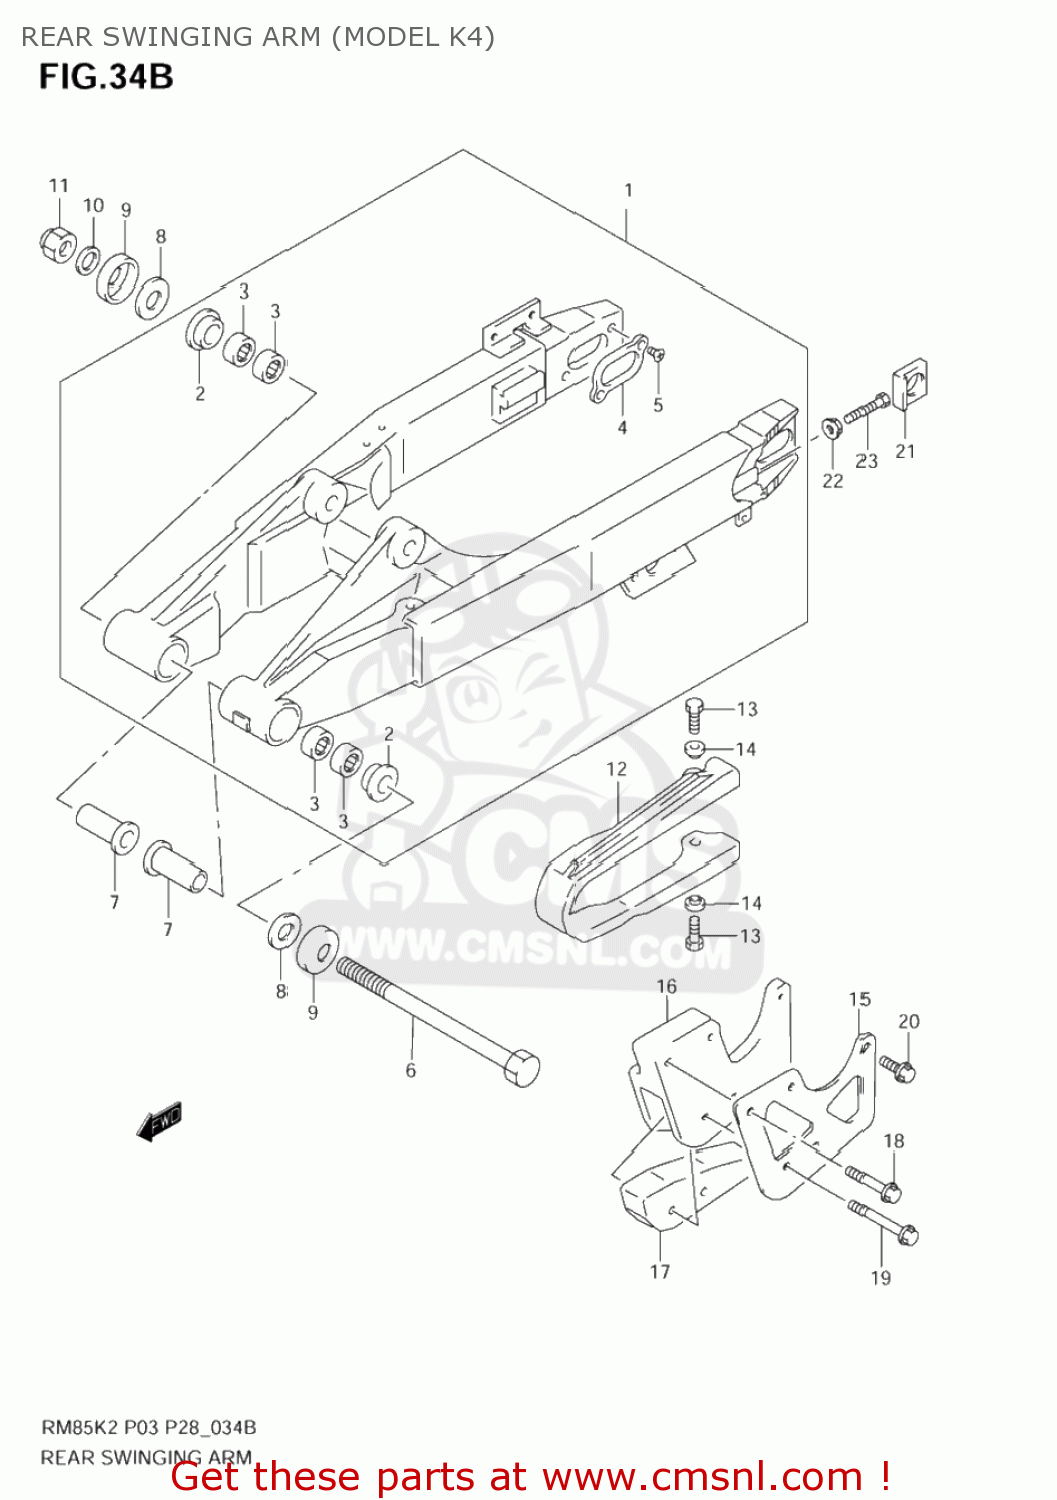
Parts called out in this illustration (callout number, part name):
1	SWINGINGARM AS
2	BUSHING,SWGARM PIVOT
3	BEARING(17X24X20)
4	PLATE,SWGARM RR
5	SCREW,UPPER
6	SHAFT,RR SWINGINGARM PIVOT
7	SPACER,RR SWGARM PIVOT
8	WASHER
9	COVER,SWGARM PIVOT
10	WASHER
11	NUT 12MM
12	BUFFER,CHAIN TOUCH DEFENSE
13	BOLT(6X16)
14	WASHER
15	PLATE,GUIDE CHAIN OUTER
16	GUIDE,CHAIN
17	DEFENSE,CHAIN GUIDE
18	BOLT(6X30)
19	BOLT(6X40)
20	BOLT(6X16)
21	WASHER,CHAIN ADJUSTER
22	NUT,ADJUSTER
23	BOLT(8X43)
